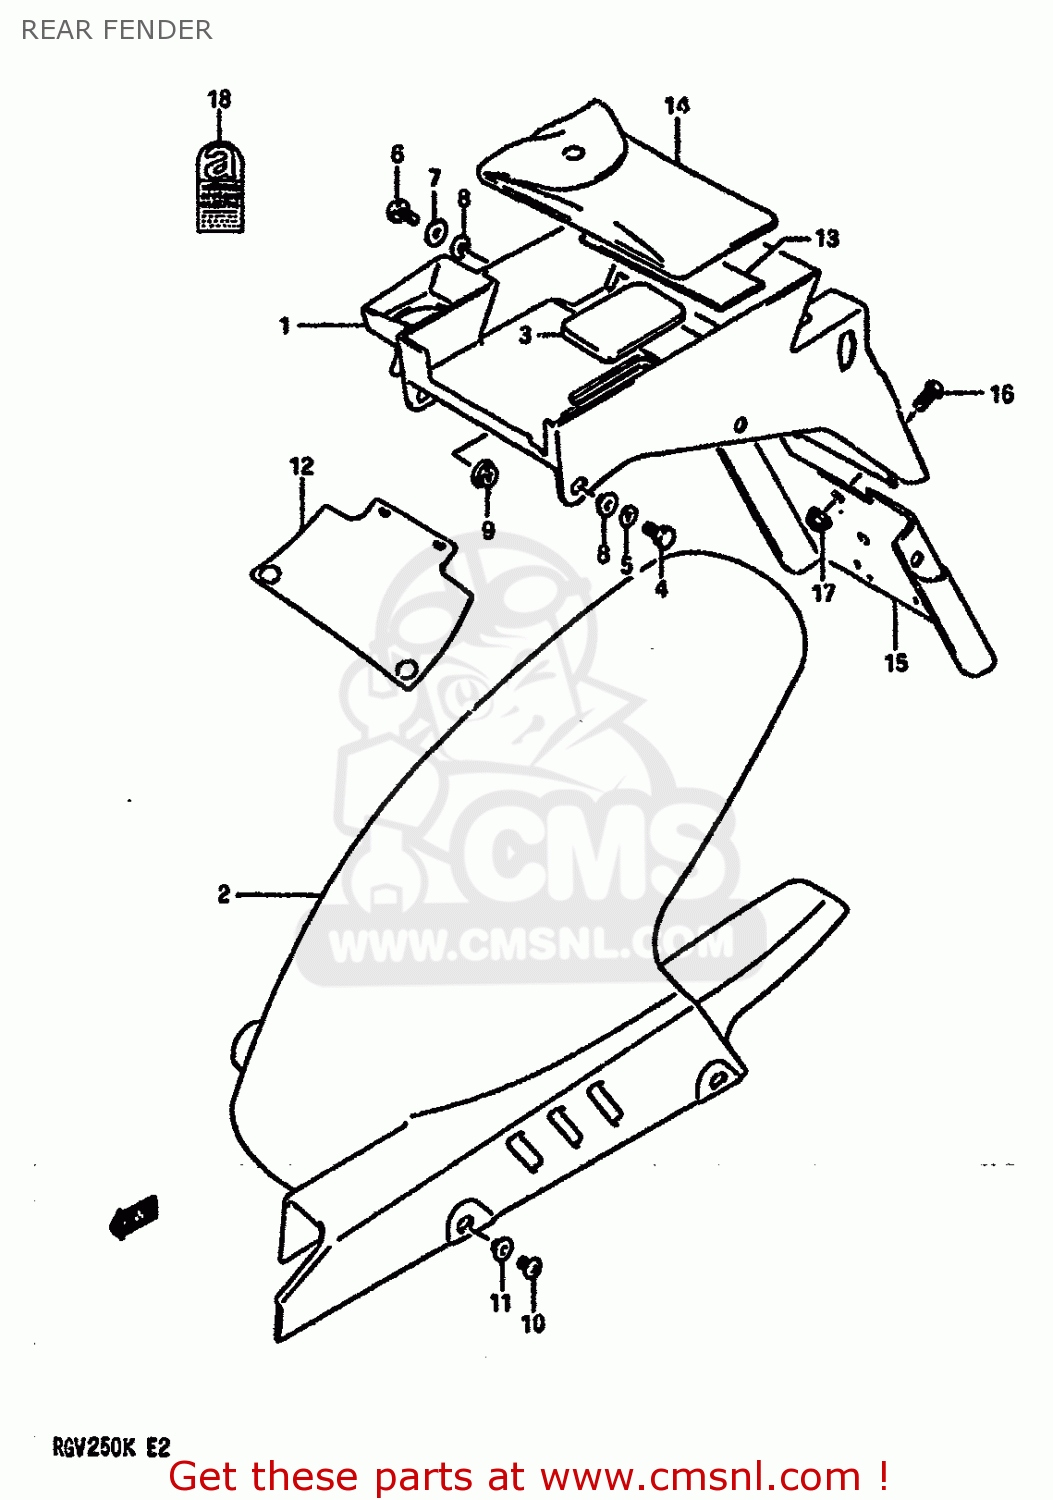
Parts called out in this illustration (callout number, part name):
1	BODY,REAR FENDER REAR
2	FENDER,REAR LOWER
3	CAP,RR FENDER RR
4	BOLT
5	WASHER,LOCK
6	BOLT
7	WASHER
8	WASHER
9	NUT 6MM
10	SCREW 6X12
11	WASHER
12	MUD GUARD,RR
13	CUSHION,TOOL HOLDER
14	TOOL ASSY
15	EXTENSION,RR FENDER
16	SCREW
17	NUT
18	LABEL,ASBESTOS WARNING
